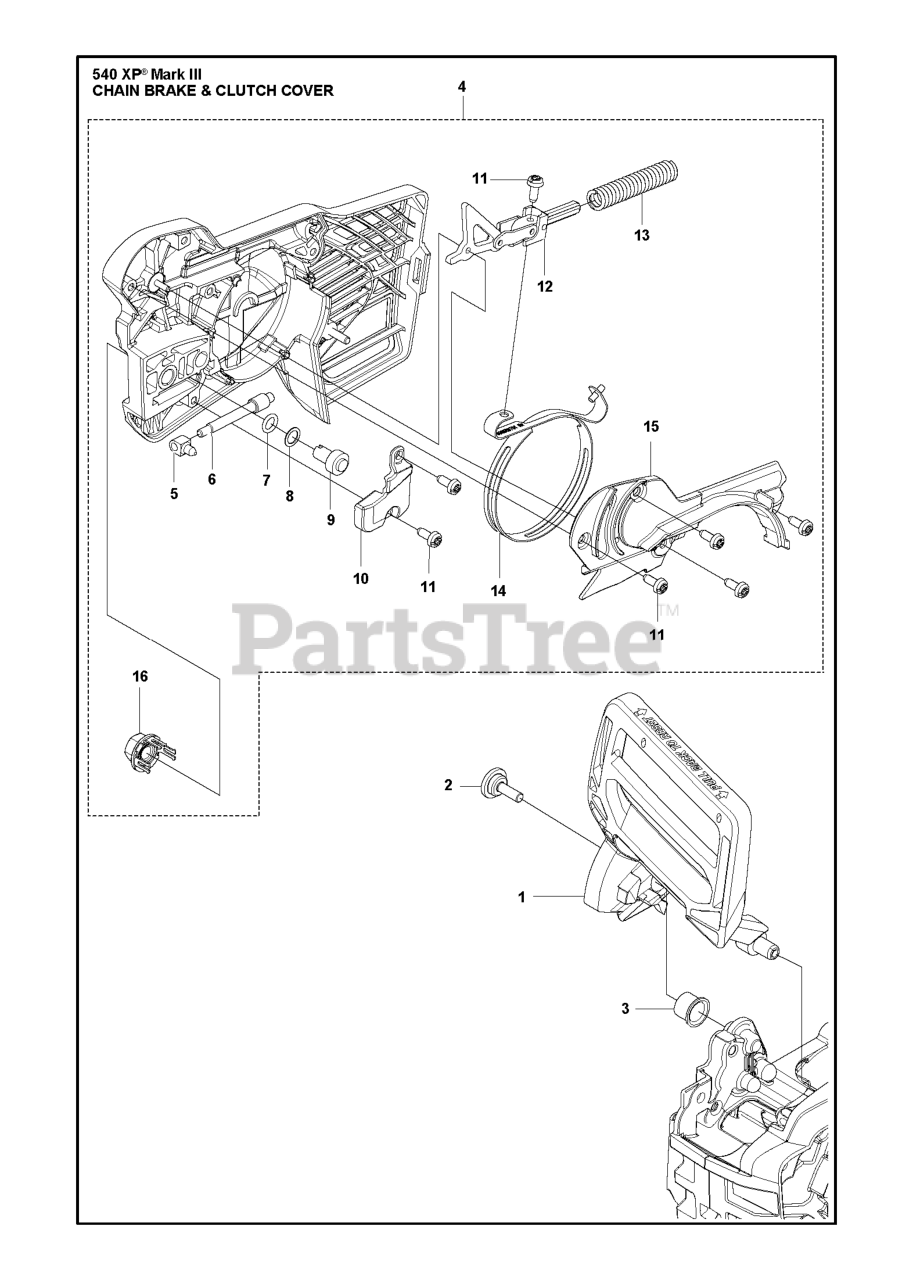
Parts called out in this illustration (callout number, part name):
5	PIN BAR ADJUSTING
9	WORM WHEEL
11	SCREW CITXPANT
12	KNEE JOINT ASSY
13	BRAKE SPRING
14	BRAKE BAND ASSY
15	COVER BRAKE COVER
16	NUT RETAINER ASSY
